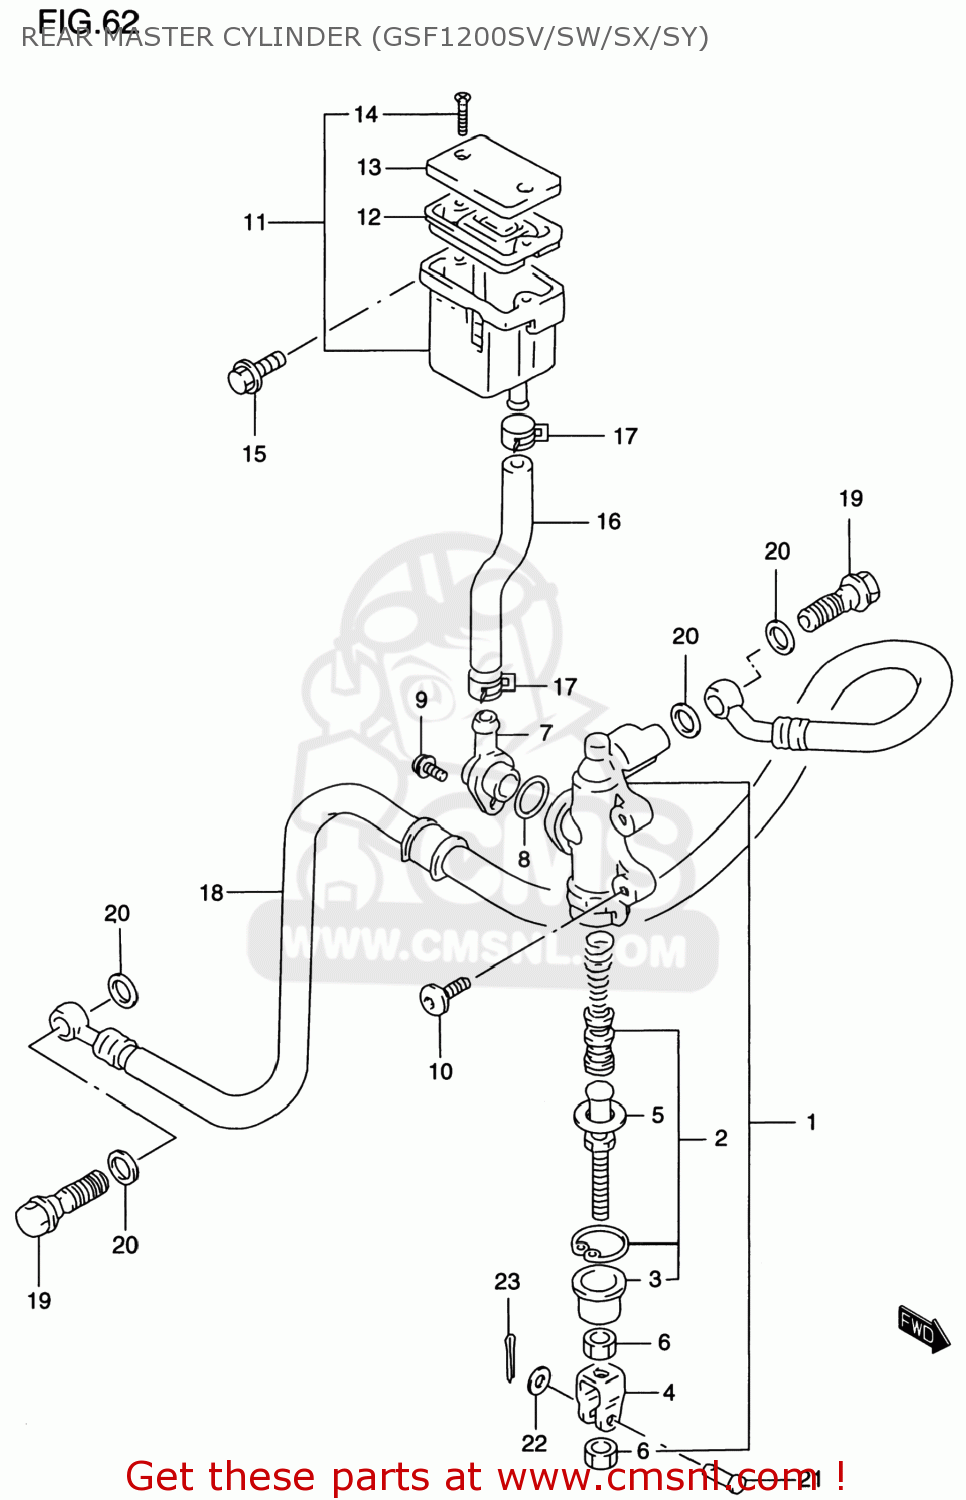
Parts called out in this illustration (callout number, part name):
1	CYLINDER ASSY,RR MASTER
2	PISTON/CUP SET
3	BOOT
4	YOKE
5	ROD,PUSH
6	NUT
7	CONNECTOR
8	O RING
9	SCREW
10	BOLT 8X20
11	TANK ASSY,RESERVOIR
12	DIAPHRAGM
13	CAP
14	SCREW
15	BOLT
16	HOSE,RESERVOIR TANK
17	CLIP
18	HOSE,RR BRAKE
19	BOLT UNION
20	WASHER(10X15X1.5)
21	PIN
22	WASHER
23	PIN
